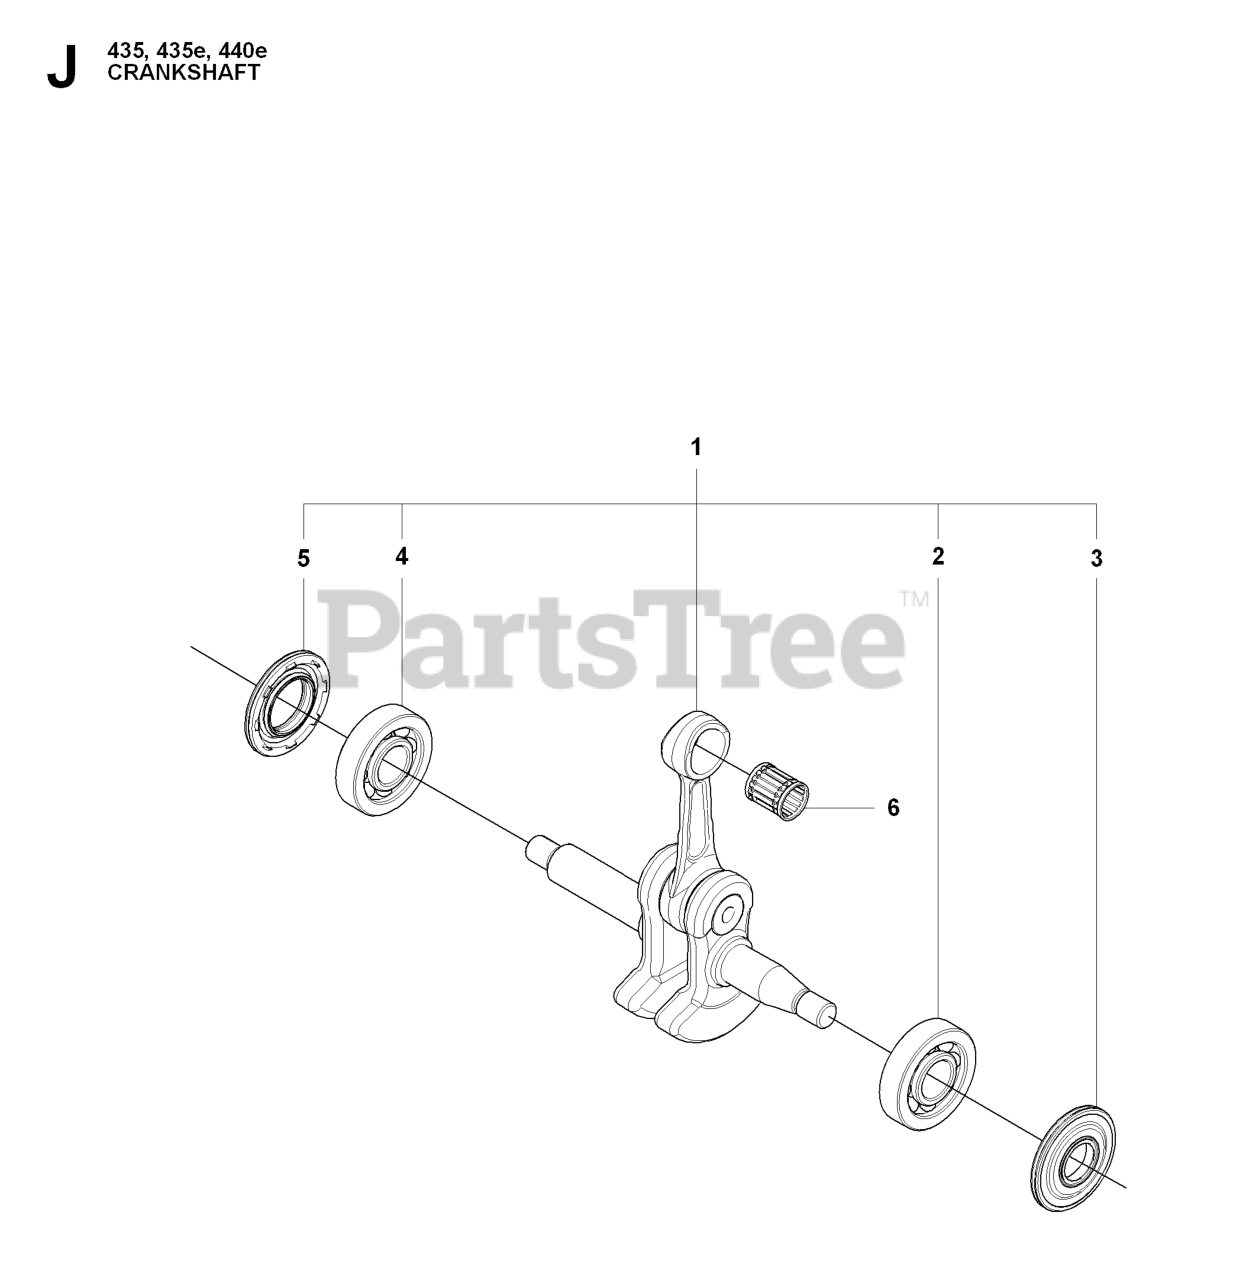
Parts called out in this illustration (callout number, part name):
1	CRANKSHAFT ASSY
2	BALL BEARING 6001 OD32
4	BALL BEARING 6001 OD32W
6	SUPPORT BUSHING
